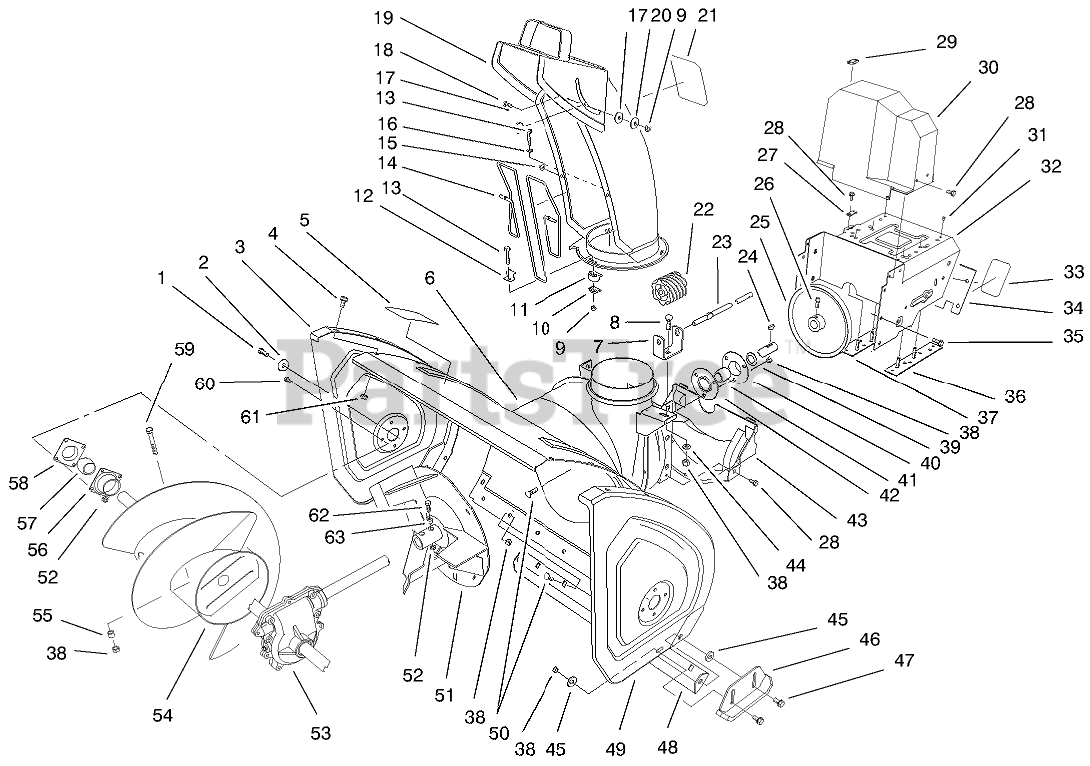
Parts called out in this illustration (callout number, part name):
1	SCREW-HH
2	WASHER
3	PLATE-SIDE, RH
4	SCREW-HHF
5	DECAL-WARNING, AUGER
5	DECAL-WARNING, AUGER (only on: 38053)
6	HOUSING
7	BRACKET-WORM, CHUTE
8	BOLT-CARR
9	NUT-LOCK, NI
10	PLATE-RETAINER, CHUTE
11	RETAINER-CHUTE
12	CLIP-GUARD, CHUTE
13	SCREW-HSH
14	GUARD-CHUTE
15	NUT-PUSH
16	WASHER-FLAT
17	WASHER-PLASTIC
19	CHUTE ASM
20	WASHER-FLAT
21	DECAL-DANGER (only on: 38078)
21	DECAL - DANGER
22	GEAR-WORM
23	ROD-CHUTE, LOWER
24	KEY-WOODRUFF
25	PULLEY-IMPELLER
26	SCREW-SET, SQH
27	RETAINER-CABLE
28	SCREW-HWH
29	COVER-CABLE
30	COVER-BELT, UPPER
31	RIVET-POP
32	ENGINE FRAME ASM
33	DECAL
34	COVER-FRAME, ENGINE
35	SCREW-HWHTF
36	LH FRAME PLATE ASM
37	RH FRAME PLATE ASM
38	NUT-LOCK, NI
39	WASHER-THRUST
40	FLANGE-CUP, BEARING
41	BEARING-BALL
42	FLANGE-CUP, BEARING
43	COVER-BELT, LOWER
44	WASHER-PLAIN
45	WASHER
46	SKID ASM
47	SCREW-HHF
48	BLADE-SCRAPER
49	PLATE-SIDE, LH
50	SCREW-CARR
51	IMPELLER-4 BLADE
52	NUT-LOCK, NI
53	LH AUGER GEARCASE ASM
54	AUGER, RH
54	AUGER, LH
55	SPACER-HUB, AUGER
56	BEARING-FLANGE, FRONT
57	BEARING
58	BEARING-FLANGE, REAR
59	SCREW-HH
60	SCREW-HH
61	NUT-LOCK, NI
62	SCREW-HHF
63	SPACER
